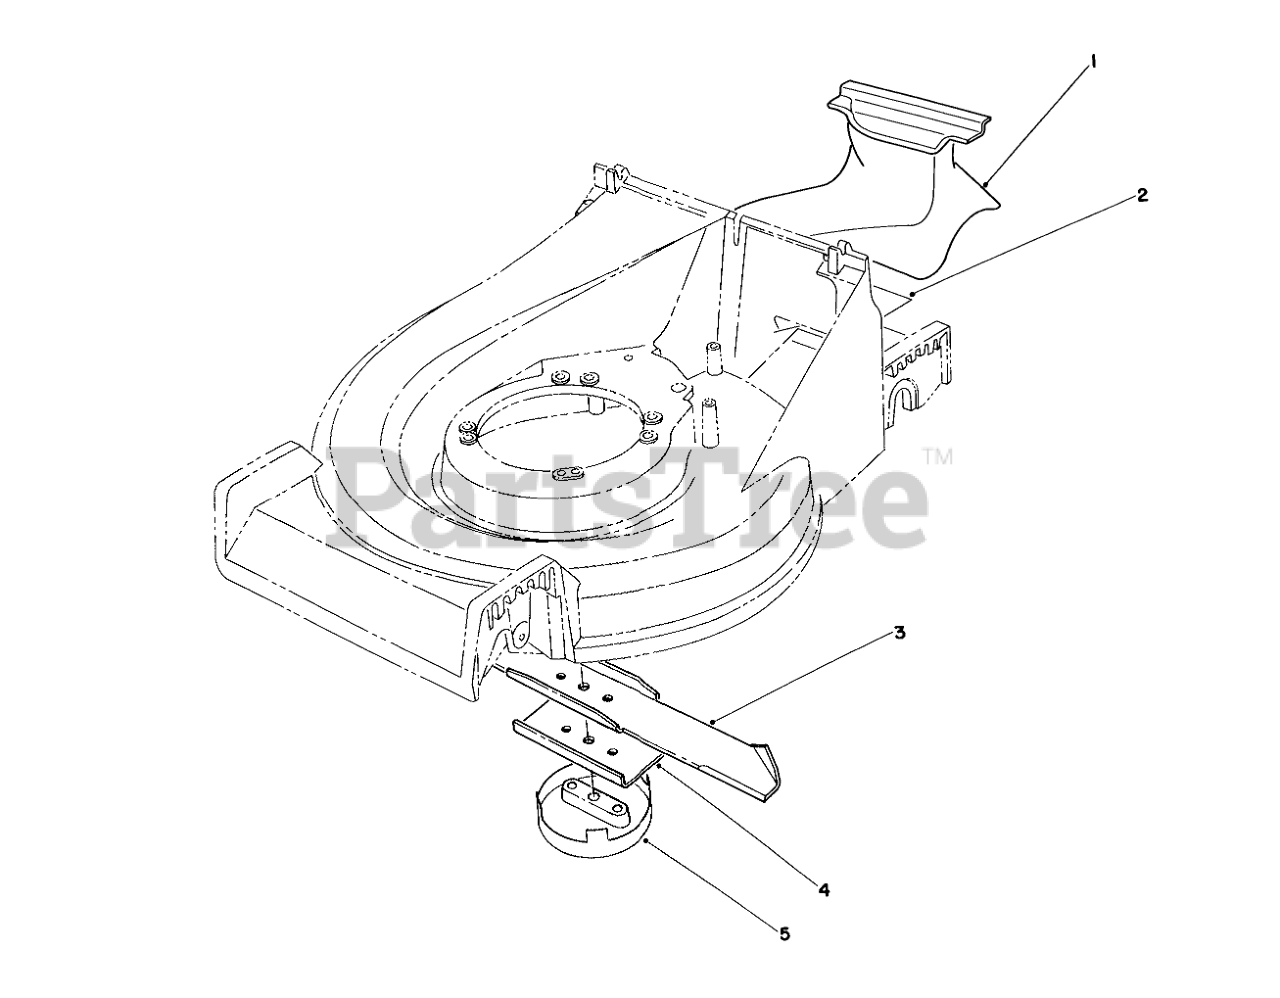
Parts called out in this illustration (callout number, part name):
1	RECYCLER PLUG
2	DECAL - MULCHER KIT
3	BLADE-21in
4	Stiffener
5	CUP-SCALP, ANTI
